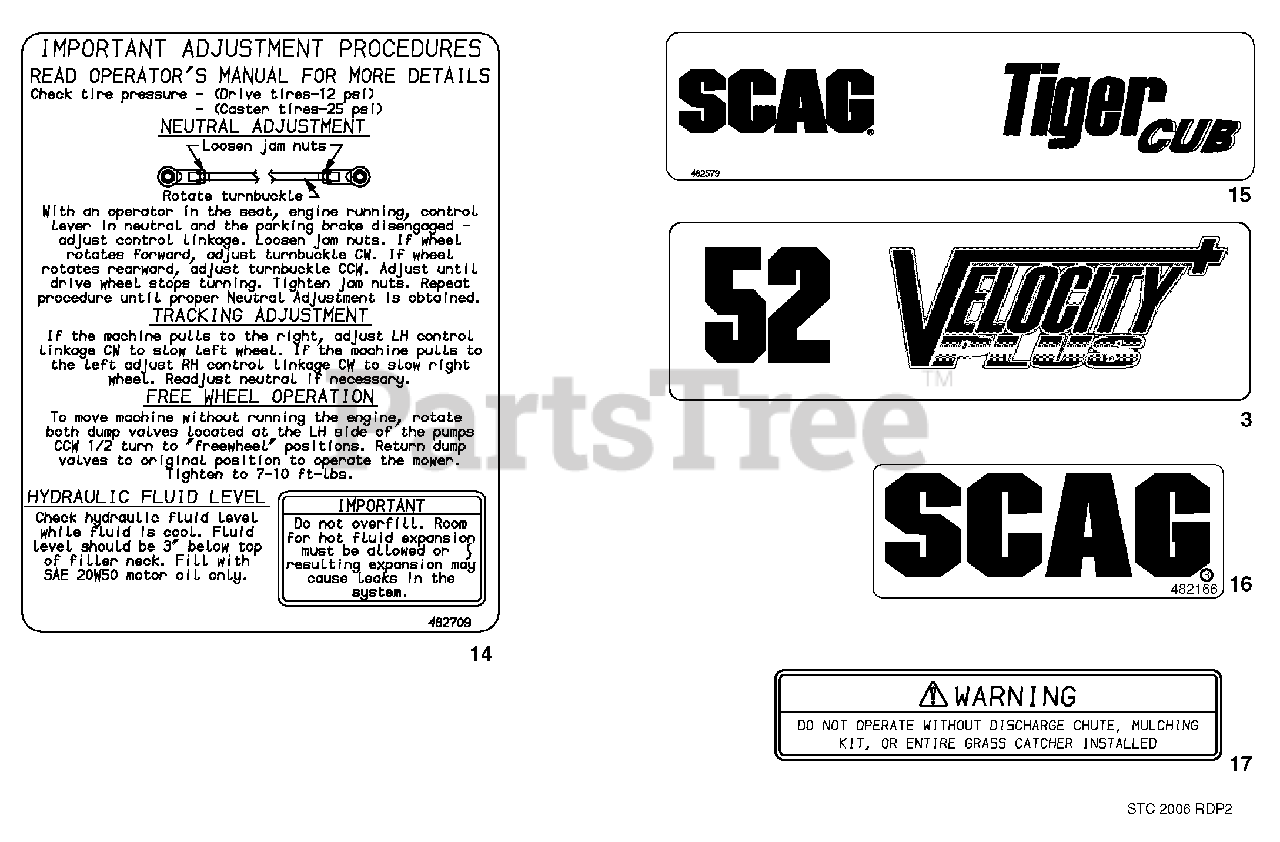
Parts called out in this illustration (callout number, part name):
3	Decal, 48V
3	Decal 52V
4	Decal, ROPS
14	Decal, Seat Support
15	Decal, Rear Bumper
16	Decal, Front Footplate
17	Decal, Discharge Chute
18	Decal, Cutting Height Top Row of Holes
